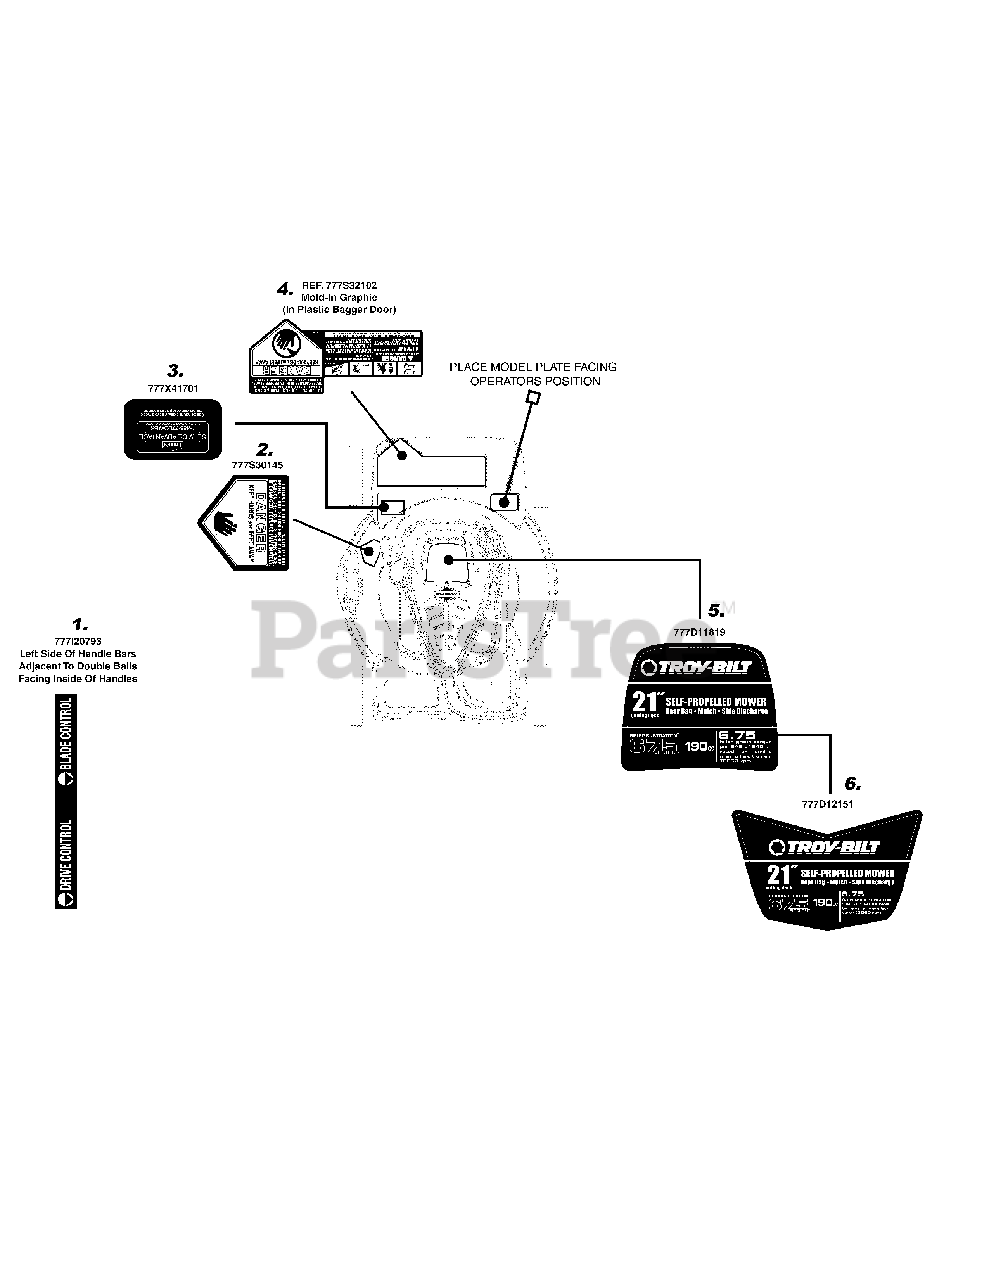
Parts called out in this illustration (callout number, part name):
1	LABEL-HANDLE
2	LABEL
4	LABEL-MOLD-IN GRAPHIC
5	LABEL-MOWER SHROUD TROY 675
6	LABEL-MOWER SHROUD TROY
